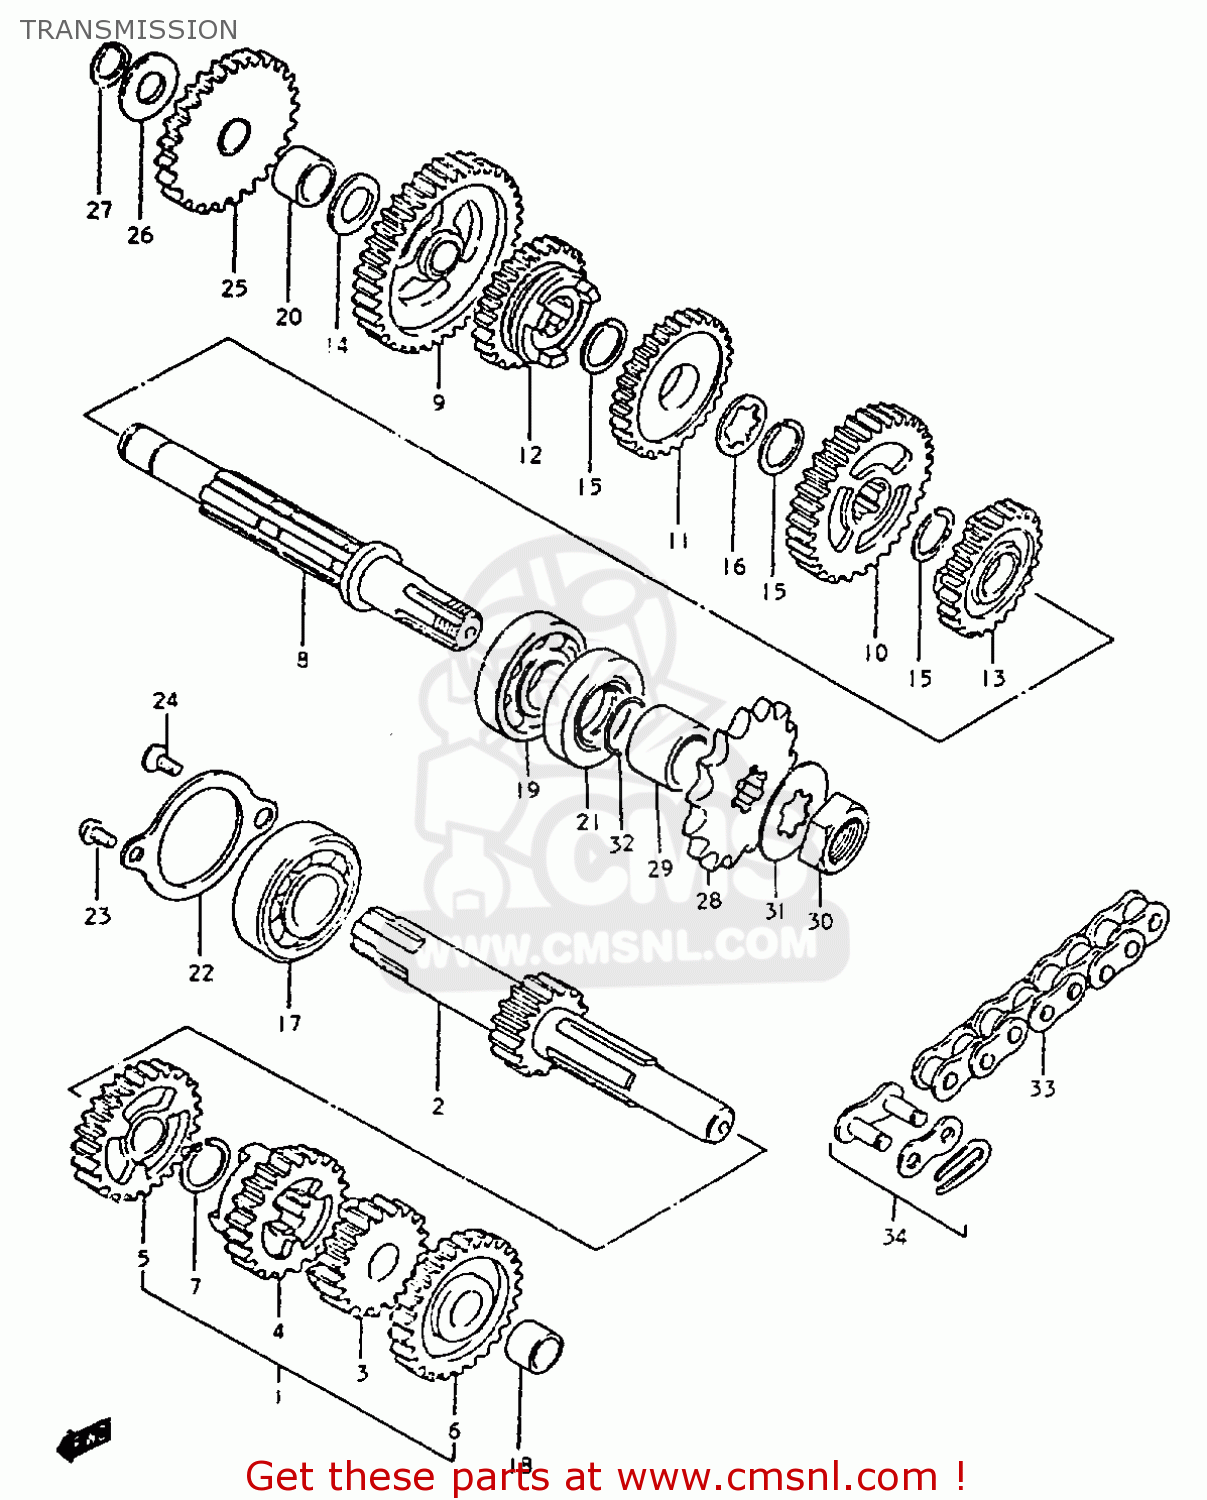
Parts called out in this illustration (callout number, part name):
1	SHAFT,COUNTER
2	SHAFT,COUNTER(NT:12)
3	GEAR,SECOND DRIVE
4	GEAR,THIRD DRIVE
5	GEAR,4TH DRIVE(NT:24)
6	GEAR,FIFTH DRIVE
7	CIRCLIP
8	SHAFT,DRIVE
9	GEAR,FIRST DRIVEN
10	GEAR,2ND DRIVEN(NT:33)
11	GEAR,3RD DRIVEN(NT:29)
12	GEAR,FOURTH DRIVEN
13	GEAR,5TH DRIVEN(NT:24)
14	WASHER(13X24X1)
15	CIRCLIP
16	WASHER,LOCK
17	BEARING
18	BUSH
19	BEARING
20	BUSH
21	SEAL,OIL(21X40X6)
22	RETAINER,CNTR SHAFT BEARING
23	SCREW
24	SCREW
25	GEAR,KICK STARTER IDLE
26	WASHER
27	CIRCLIP
28	SPROCKET,ENGINE(NT:12)
29	SPACER(17X21X13)
30	NUT
31	WASHER,LOCK
32	O RING(D:1,ID:16.8)
33	CHAIN ASSEMBLY,DRIVE
34	JOINT ASSEMBLY,CHAIN
